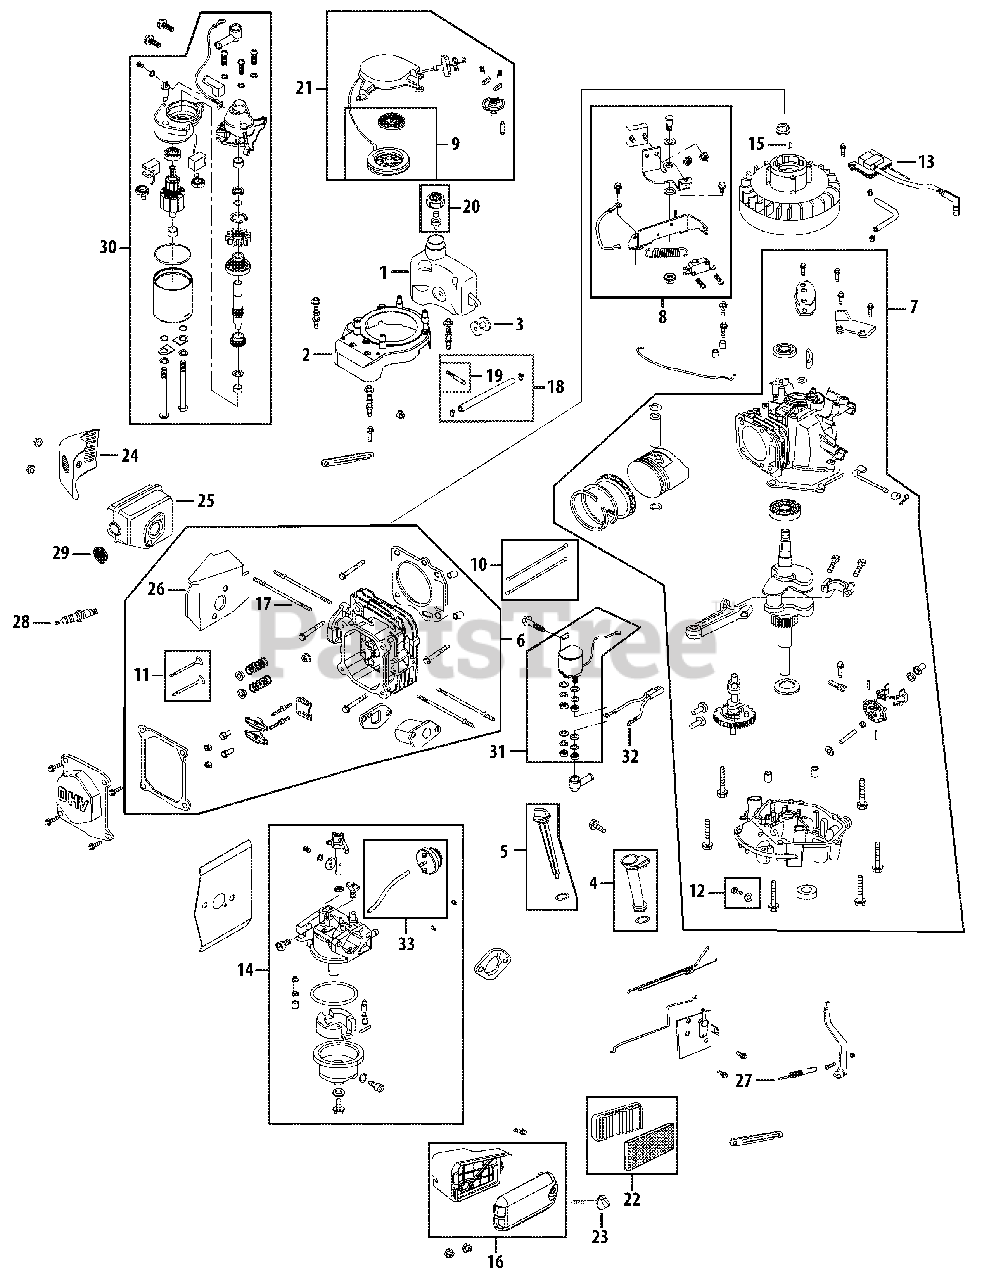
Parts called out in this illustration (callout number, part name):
1	Fuel Tank
2	Flywheel Shroud
3	Rubber Fuel Tank Mounting Washer
4	Oil Filler Tube Assembly
5	Dipstick Assembly
6	Cylinder Head Complete
7	Short Block Assembly
8	Stop Switch and Brake Assembly
9	Recoil Spring and Pulley Assembly
10	Push Rod Kit
11	Valve Kit
12	Oil Drain Plug and Washer Assembly
13	Ignition Coil
14	Carburetor Assembly
15	Flywheel Key
16	Air Cleaner Housing Assembly Complete
17	Muffler Stud Assembly
18	Fuel Line Kit
19	Fuel Filter
20	Fuel Cap Assembly
21	Recoil Starter Assembly
22	Air Cleaner Kit
23	Air Cleaner Thumb Screw
24	Muffler Guard
25	Muffler
26	Muffler Gasket /Heat Shield
27	Governor Return Spring
28	Spark Plug
29	Spark Arrestor
30	Electric Starter
31	Relay Assembly
32	Relay Harness Connector
33	Primer Assembly
